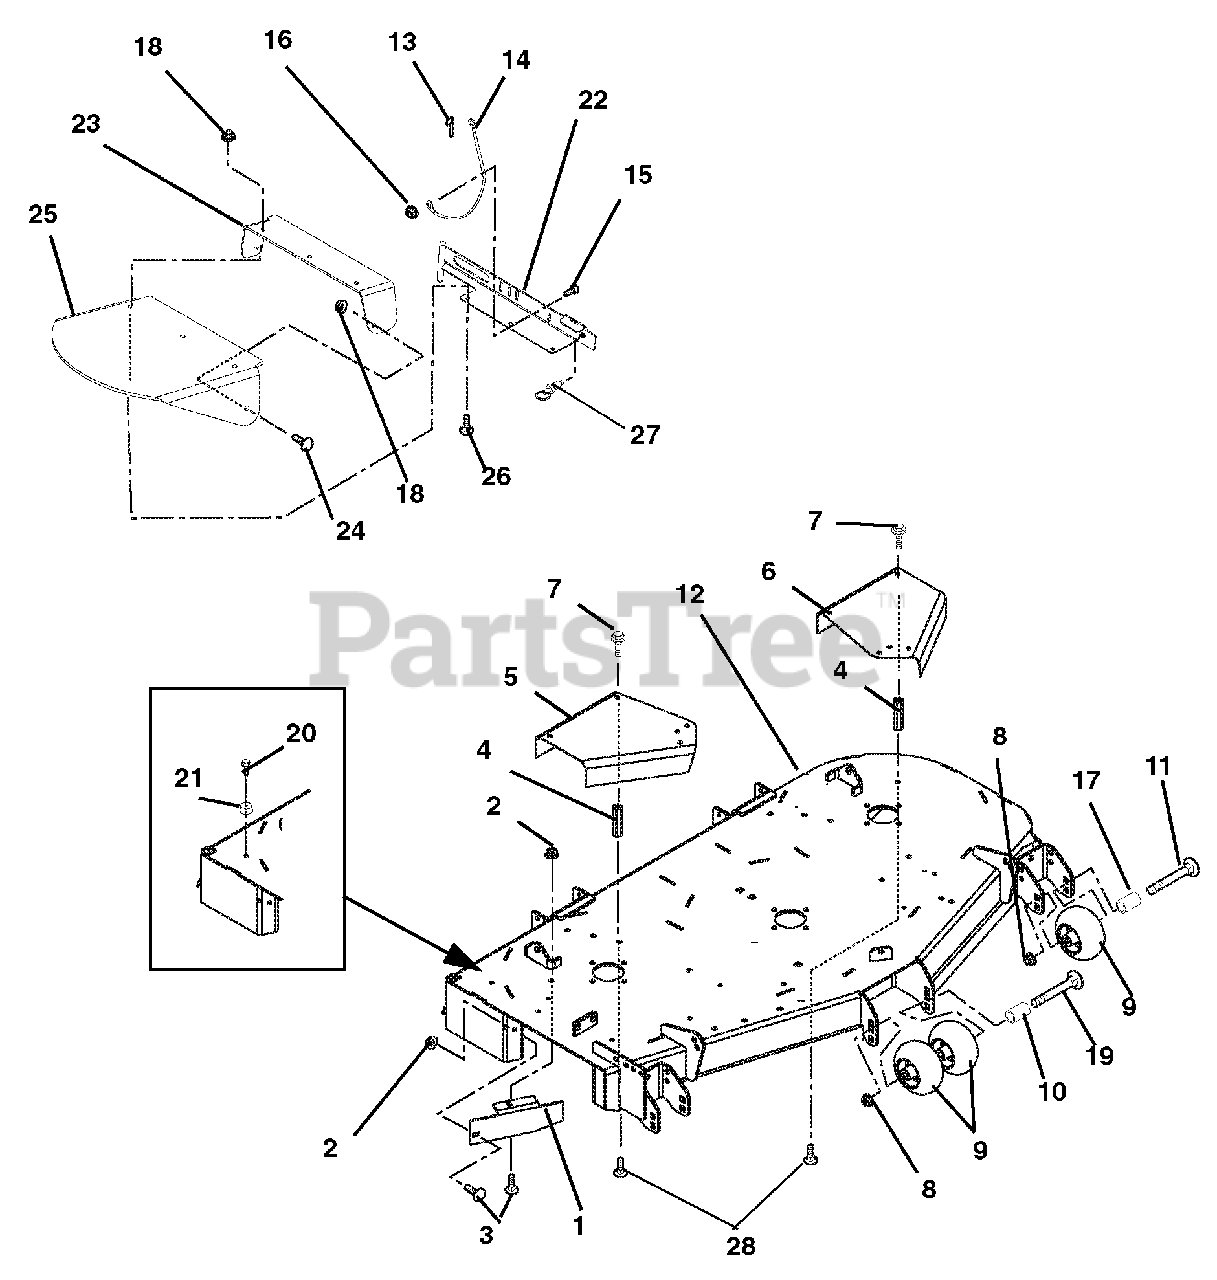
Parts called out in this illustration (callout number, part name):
1	44 in. & 48 in. Rear Discharge Baffle (991026, 027, 029, 032)
2	Nut, .31-18 Nyloc Flange
3	Bolt, Round Head Square Neck .31-18 x 1.00 Grade 5
4	Nut, Coupling .31-18 x 3.00
5	44 in. Right Hand Spindle Guard (991026, 032)
6	44 in., 48 in., & 52 in. Left Hand Spindle Guard
7	Bolt, SEMS .31-18 x .62
8	Nut .50-13 Nyloc Flange
9	Anti-Scalp Wheel
11	Bolt, Round Head Square Neck .50-13 x 5.00
12	44 in. Mower Deck (991026, 032)
13	Pin, Spring Ball .375 OD x 1.50
14	Cable, 5-in.
15	Bolt, Hex .25-20 x .75 Grade 5
16	Nut, Locking Top Flange .25-20
17	Spacer, .510 x .625 x 3.35
18	Nut, .38-16 Nyloc Flange
19	Bolt, Round Head Square Neck .50-13 x 8.50
20	Screw, Tapping .31-18 x .75 Hex Washer Head Thread
21	Bumper, Recessed 1.50 x .63 , .31 Thru Hole
22	52 in. & 60 in. Discharge Chute Mounting Weldment (991028, 030, 031, 042)
23	Rubber Discharge Chute Support
24	Bolt, Round Head Square Neck .38-16 x 1.00 Grade 5
25	Chute, Rubber Discharge
26	Bolt, Round Head Square Neck .38-16 x 1.25 Grade 5
27	Pin, Pull
28	Bolt, Round Head Square Neck .31-18 x .75 Loctite
